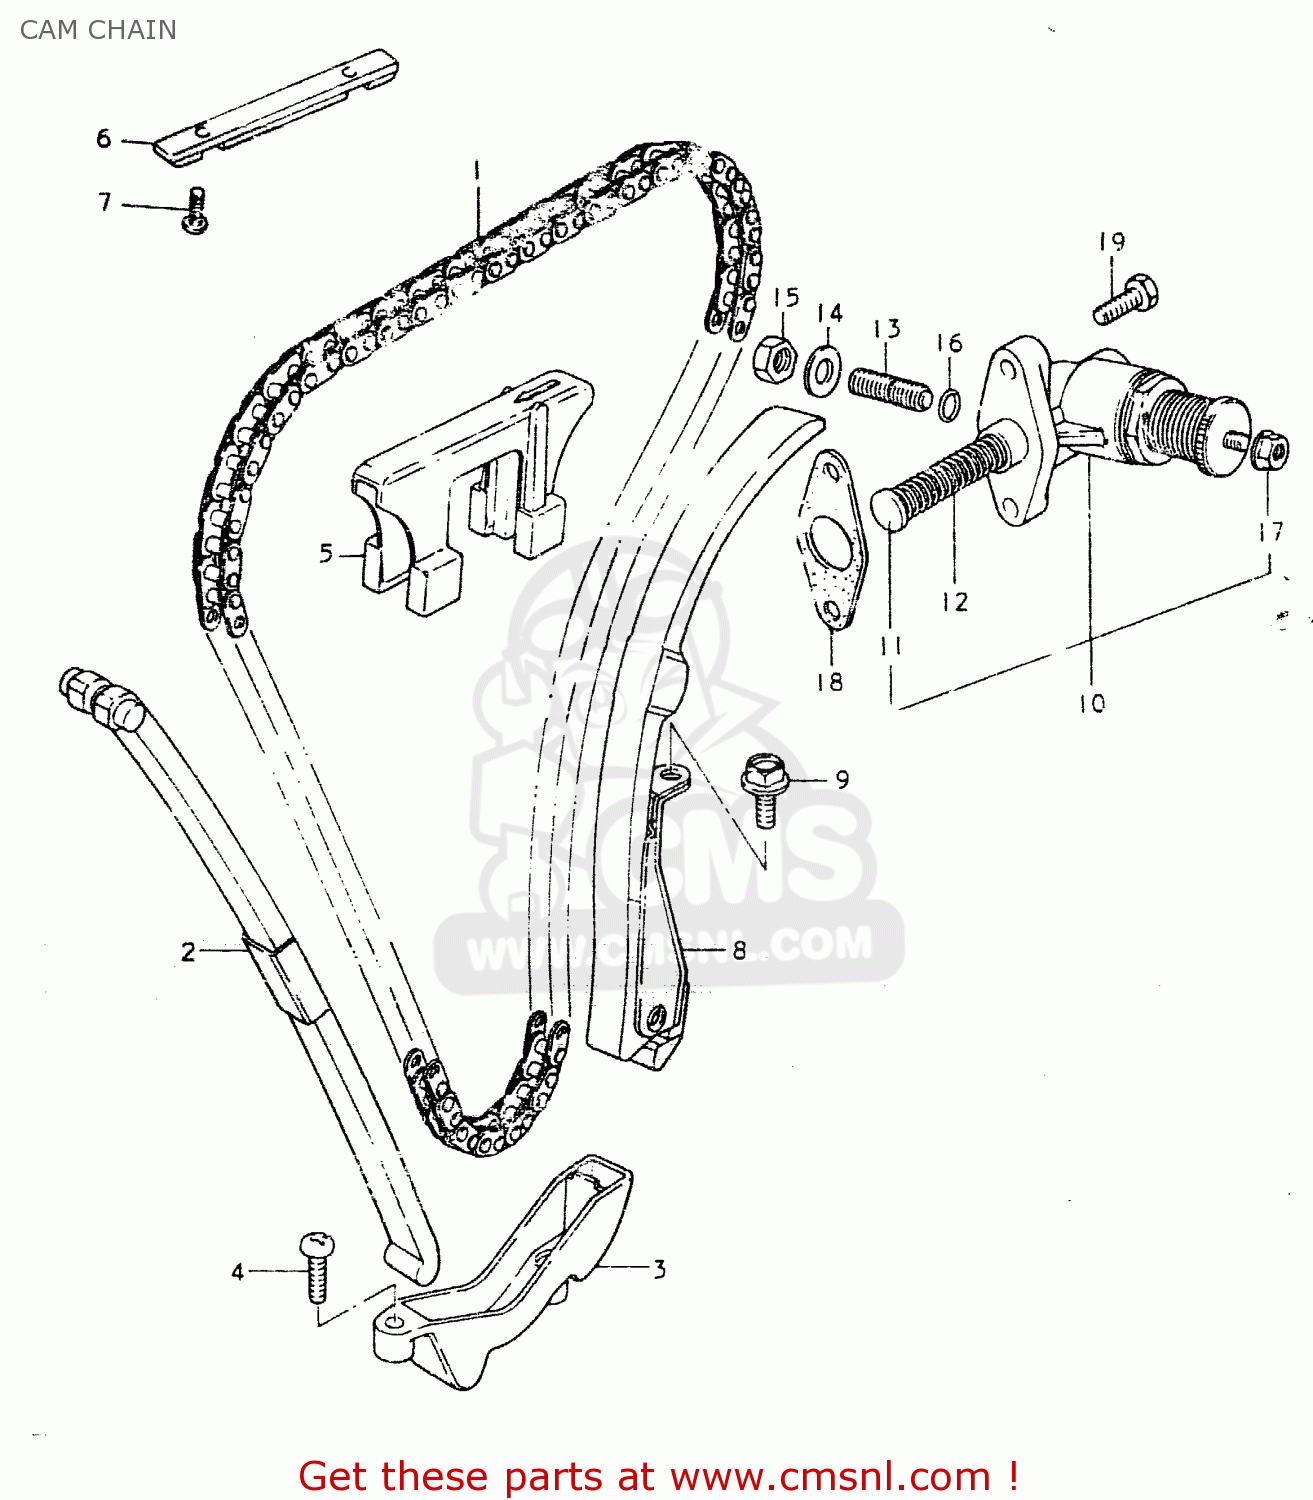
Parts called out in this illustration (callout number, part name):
1	CHAIN,CAMSHAFT DRIVE
2	GUIDE,CAM CHAIN NO.1
3	HOLDER,CAM CHAIN GUIDE
4	SCREW
5	GUIDE,CAM CHAIN NO.2
6	GUIDE,CAM CHAIN NO.3
7	SCREW
8	TENSIONER,CAM CHAIN
9	BOLT
10	ADJUSTER ASSEMBLY,TENSIONER
11	ROD,PUSH
12	SPRING
13	SCREW
14	WASHER
15	NUT
16	O-RING
17	NUT
18	GASKET,TENSIONER ADJUSTER (MCA)
19	SCREW
